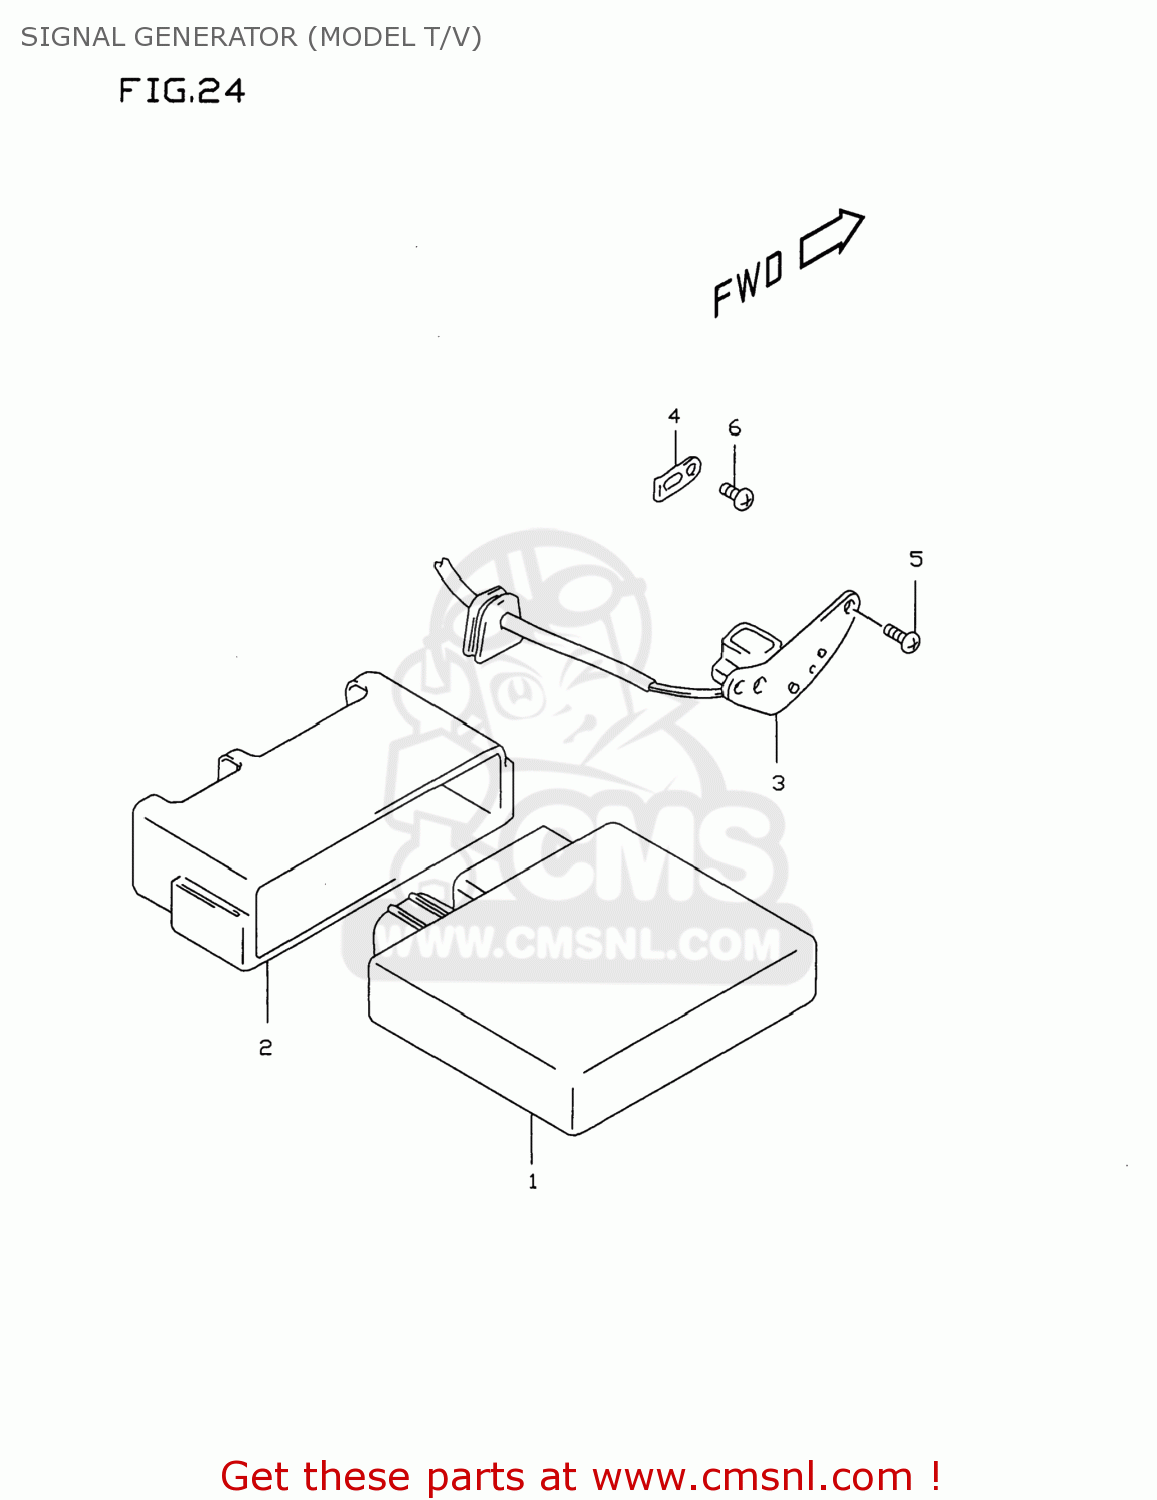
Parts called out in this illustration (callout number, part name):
1	IGNITER ASSEMBLY
2	CUSHION,IGNITER
3	STARTER,SIGNAL GENERATOR
4	CLAMP,SIGNAL GENERATORERATOR
5	SCREW
6	SCREW
